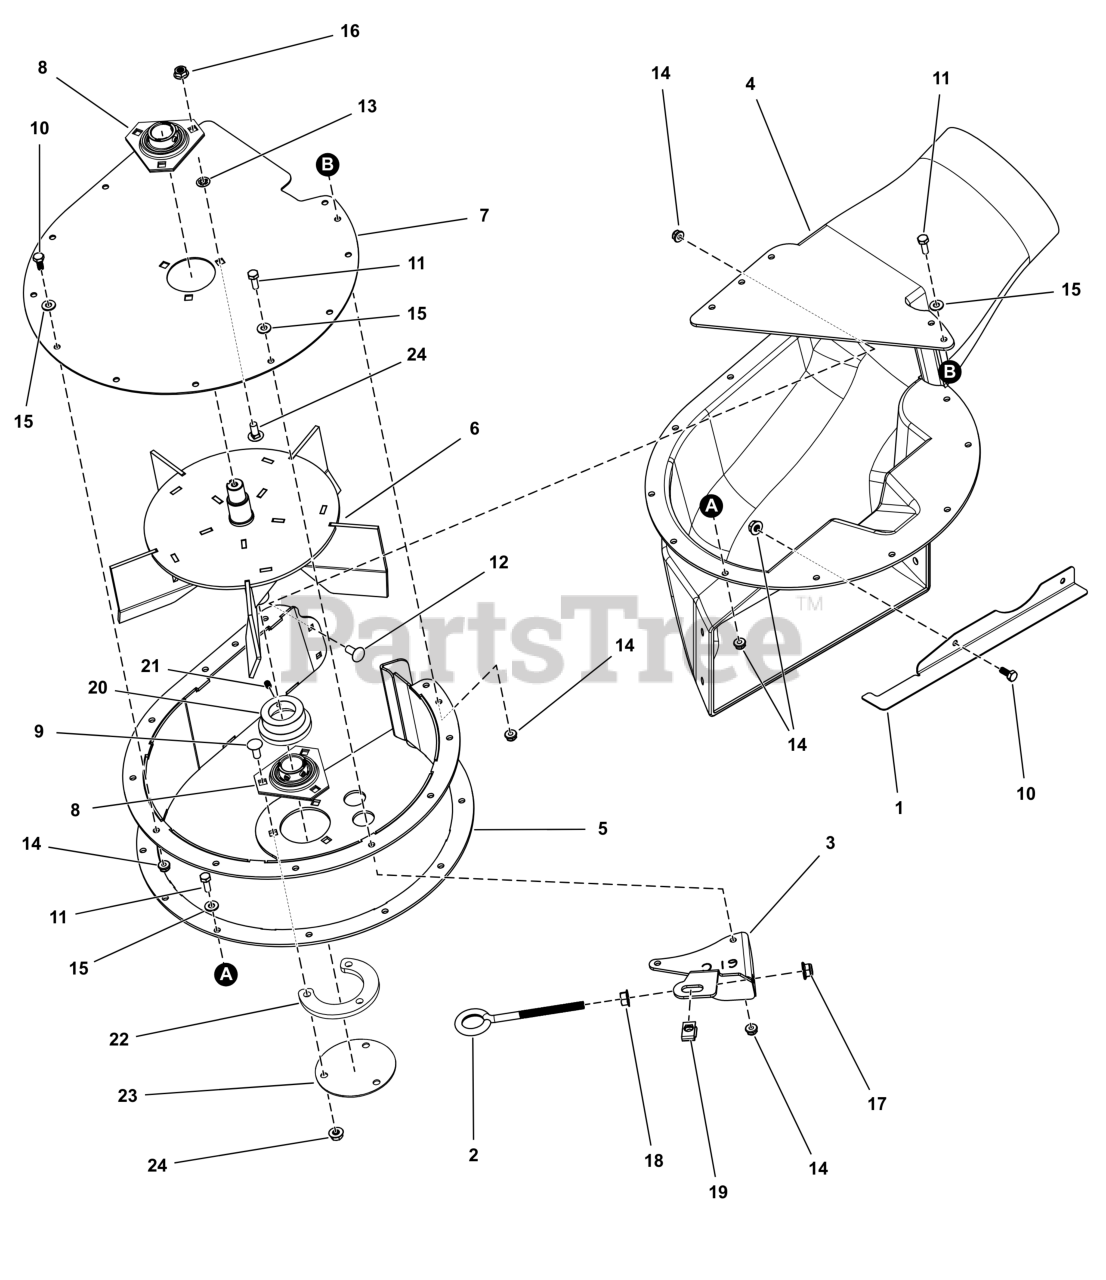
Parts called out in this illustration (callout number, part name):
1	BRACKET, ADAPTER SEAL, COM BLOWER - BLK
2	EYE BOLT, 3/8-16 X 6, 3THRD, 1EYE, CZ
3	WELD, SPRING ANCHOR, COM - BLK
4	MOLDED HOUSING, COMMERCIAL TURBO VAC
5	WELD, FAN CAGE, BLOWER - BLK
6	WELD, FAN ASSEMBLY, TMAX
7	PLATE, FAN, TOP - BLK
8	BEARING, 3 BOLT STEEL FLANGE, 1" BORE
9	BOLT, 5/16-18 X 1, CARRIAGE, GD5, CZ
10	HHCS, 1/4-20 X 0.625, GR5, ZINC/CLEAR
11	BOLT, 1/4"-20 X 3/4" GD5 YZ
12	BOLT,1/4-20X0.750,GR5,STD NECK,SQ,ZC/CL
13	5/16" PUSH-ON NUT RETAINER, STL, CZ
14	NUT, 1/4-20 Hex Nylock Flange
15	WASHER, 1/4 SAE
16	NUT, 5/16-18 HEX SERRATED FLANGE (SMALL)
17	NUT, 3/8 - 16 HEX NYLOCK FLANGE
18	NUT, 3/8-16 Hex Large Serrated Flange
19	BODY CLIP, 5/16-18 7GA. MATERIAL
20	GUARD, BEARING, TMAX
21	SET SCREW, 1/4-20 X 3/8, KNURLED CUP
22	PLATE, C-SHAPED SPACER, TMAX - BLK
23	PLATE, INNER COVER, TMAX - BLK
24	RHSSNB,5/16-18 X 3/4 GR5 ZINC/CLEAR
